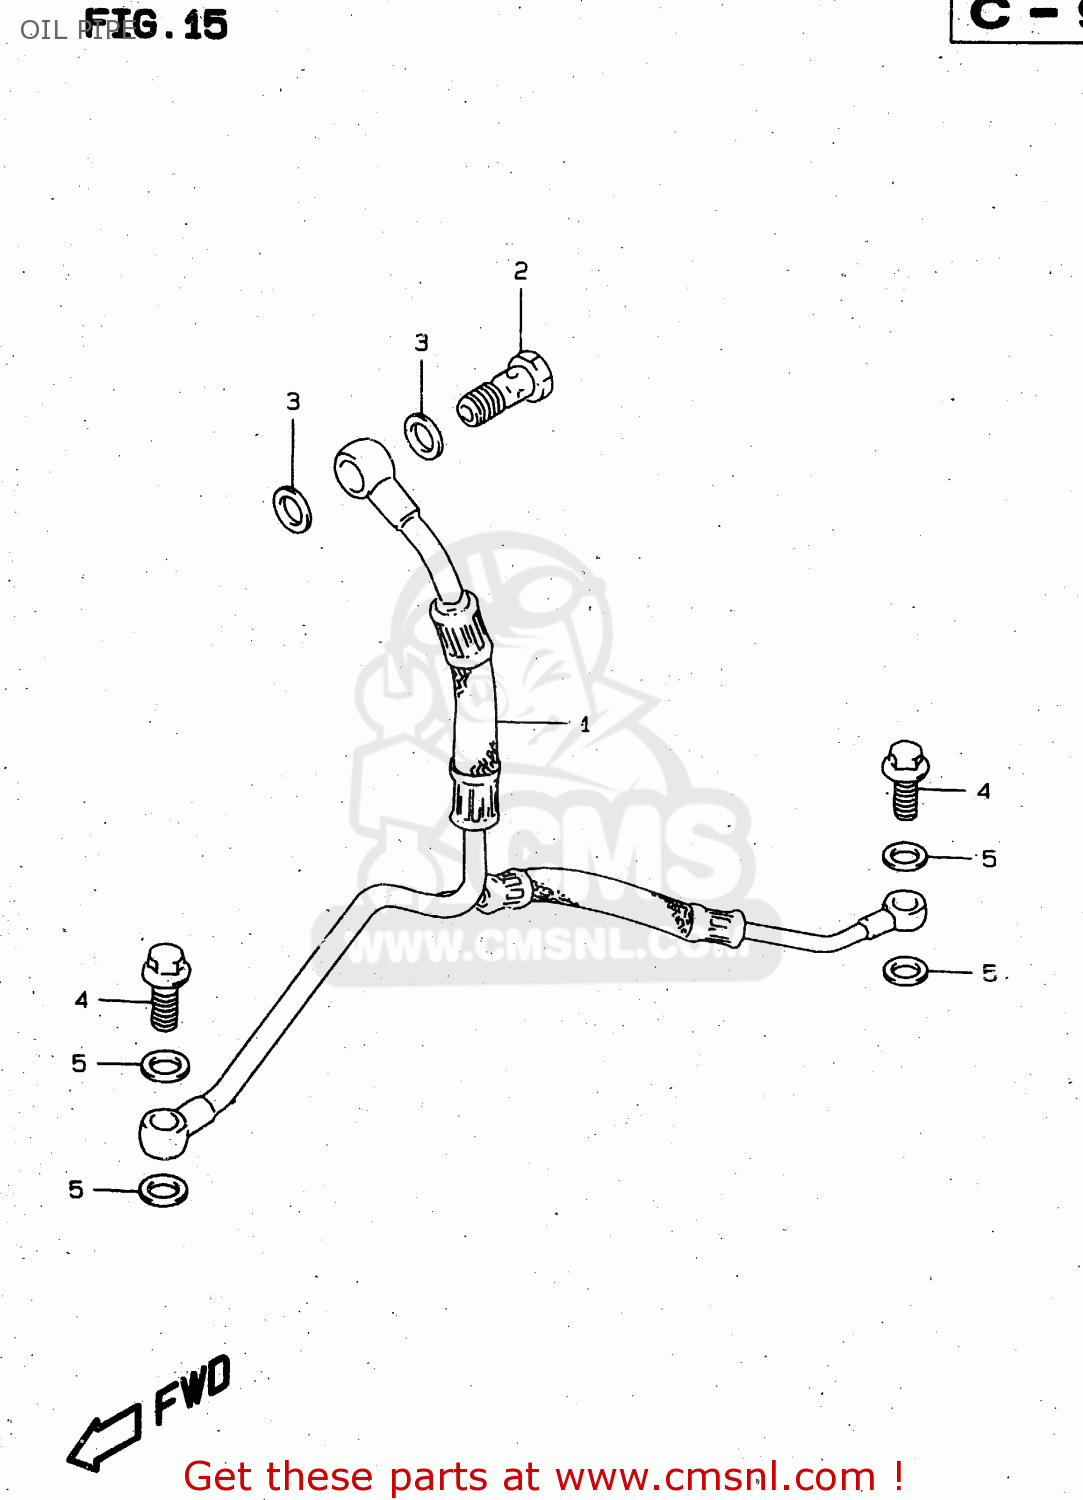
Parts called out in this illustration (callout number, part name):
1	PIPE,T/M & CSHAFT OIL
2	BOLT UNION
3	GASKET(12X17X1) (NAS)
4	BOLT UNION
5	GASKET(10.1X16X1) (NAS)
